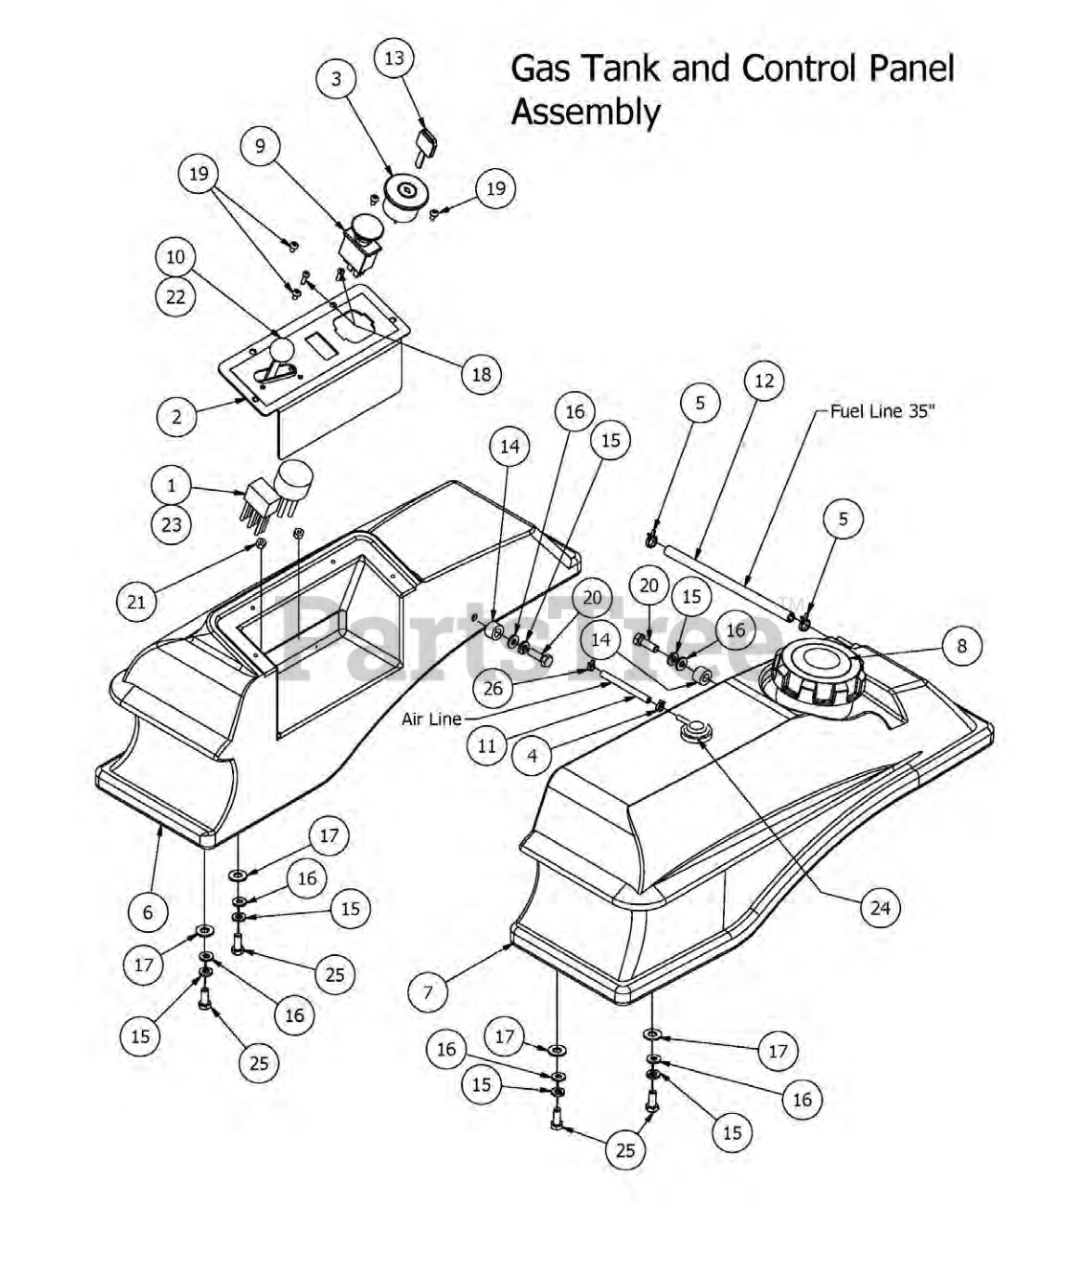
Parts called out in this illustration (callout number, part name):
1	Wiring harness
2	MZ Control Panel
3	Ignition Switch
4	1/4" Hose Clamp
5	1/4 Fuel Hose Clamp
6	Fender Console
7	3 Gallon Fuel Tank/MZ/2012 EPA
9	PTO Engager
10	Throttle Lever Kohler Only
11	3/16" clear viynl tubing
12	1/4" fuel line hose sold by the Foot
13	Ignition Key
14	Tank spacer
15	5/16" Lock Washer
16	1/4" Flat Washer
17	.360 ID Plastic Washer
18	10-24 X 5/8 BS Button Head Bolt
19	10-32 x 3/8" Button Socket Head Bolt
20	5/16" x 1 1/4" Bolt
21	10-24 Nylon Insert Locknut
22	Throttle-21Hp MZ Only
23	Relay Terminal
24	Rollover Valve-White
25	5/16" x 3/4" Hex Bolt
26	3/16" Vinyl Hose Clamp
